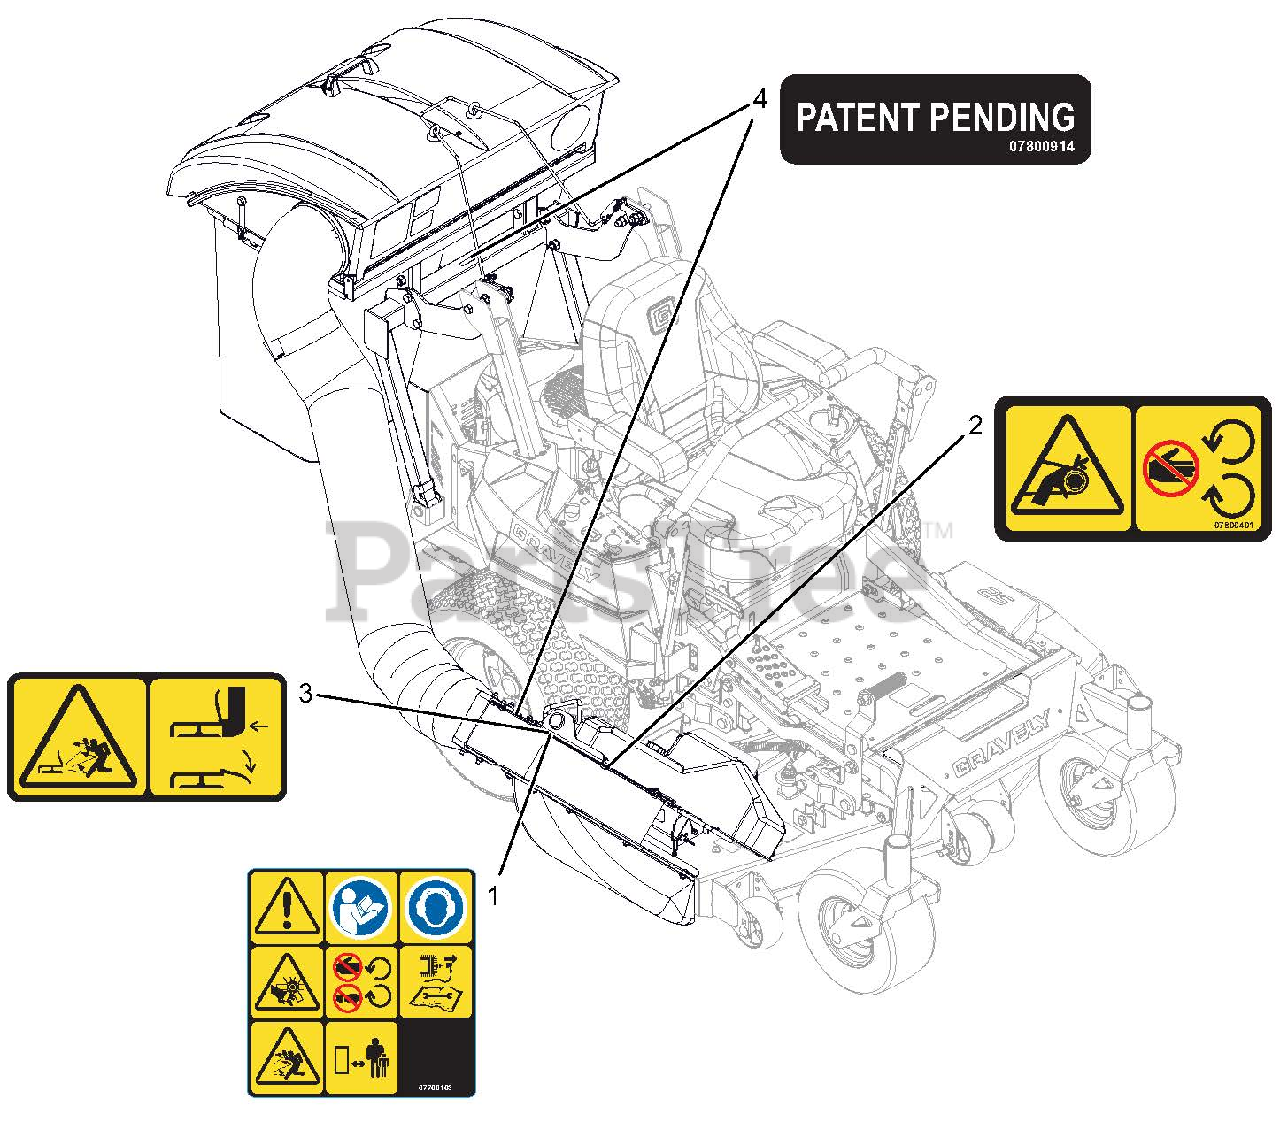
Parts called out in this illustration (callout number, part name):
1	DECAL,VAC WARNING ISO
2	DECAL, SAFETY - GUARDING
3	DECAL, SAFETY - DECK GUARDING
4	DECAL, PATENT PENDING
